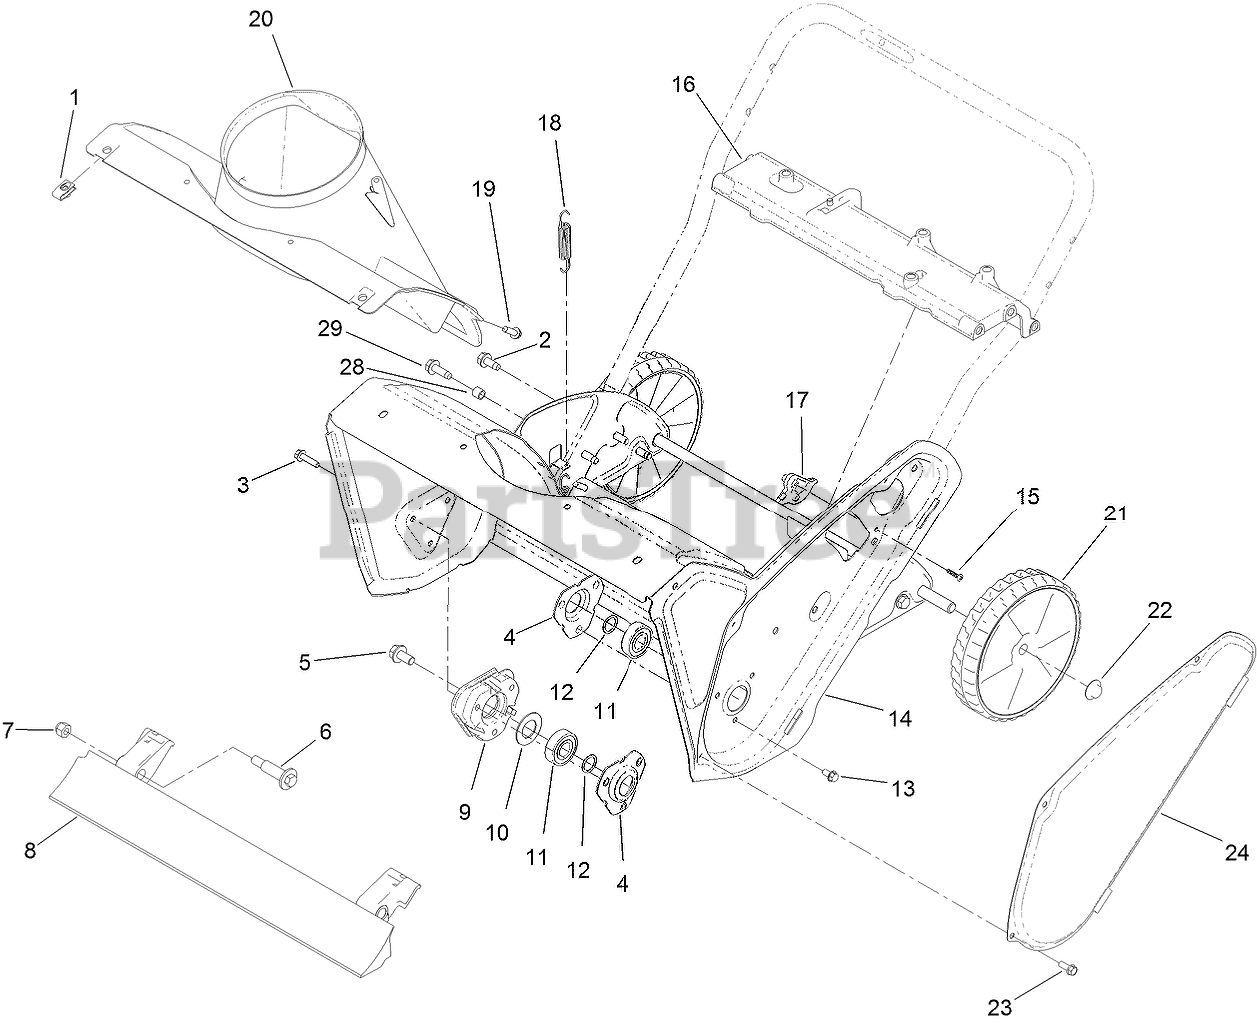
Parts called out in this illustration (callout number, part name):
2	SCREW-THD ROLL, HWH
3	SCREW-HWHTF
4	FLANGE-BEARING
5	SCREW-HWH
6	BOLT-SHOULDER
7	NUT-LOCK, NI
8	BLADE-SCRAPER
9	SPACER-BEARING, RH
10	WASHER-RUBBER
11	BEARING-BALL
12	WASHER-THRUST
13	SCREW-HWH
14	HOUSING-AUGER
15	SCREW-PPH
16	BRACE-FRAME
17	GUIDE-CABLE, CLUTCH
18	SPRING-EXTENSION
19	SCREW-HWH
20	CHUTE-LOWER
21	WHEEL ASM
22	NUT-PUSH
23	SCREW-HWH
24	COVER-BELT
28	SPACER-GROMMET
29	SCREW-HWHTF
